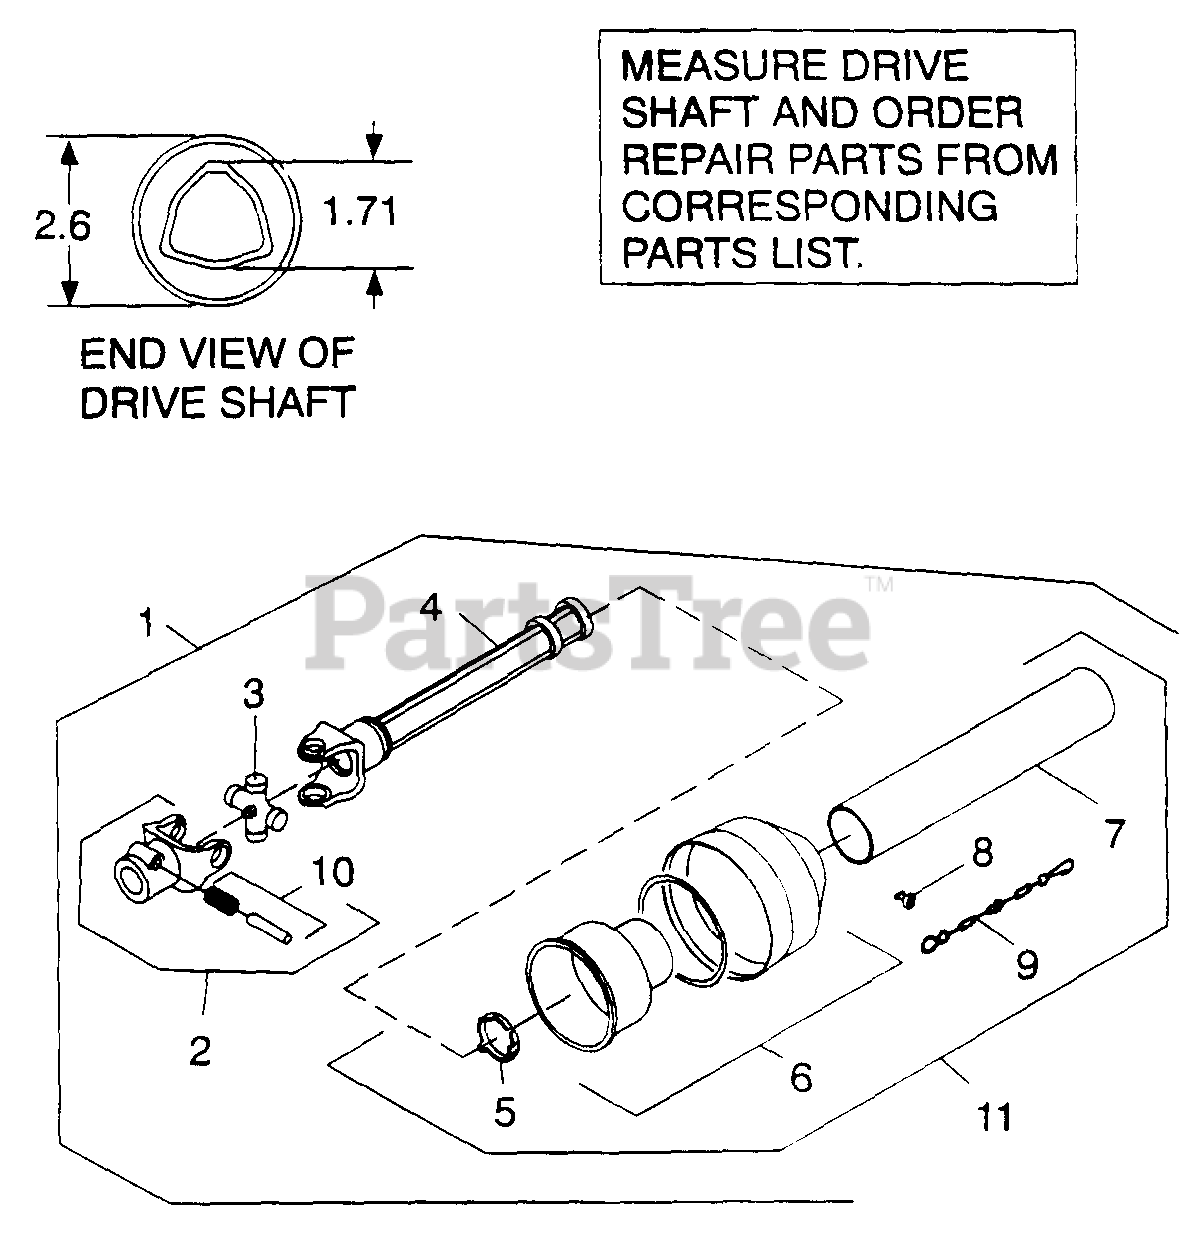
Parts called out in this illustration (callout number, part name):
1	Drive, Profile shield 40, 25.1, 1.38
2	Yoke 40, 1-3/8 QD
2	Yoke 40, 4.37 x 3.04 x 1-1/8
3	U-Joint repair kit 40
4	Yoke and tube, Profile 40, 25.1
5	Shield bearing kit 40
8	Shield retainer
9	Shield tether chain
10	1-3/8 Push pin set
11	Shield assembly, non-rotating 2.62 x 2.44 x 26.9
